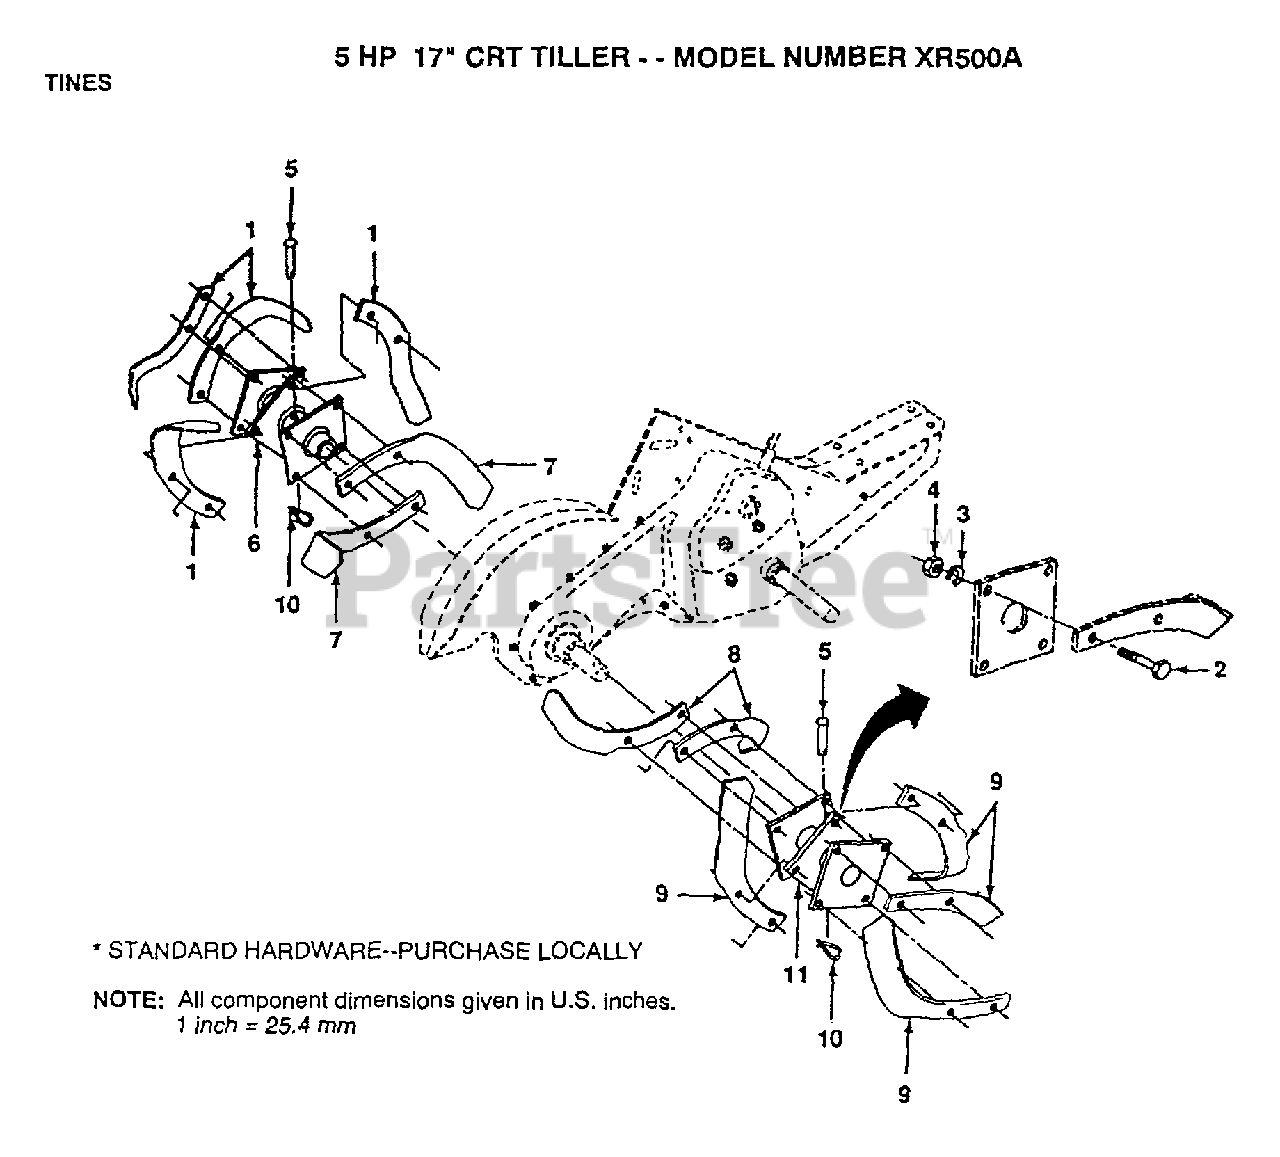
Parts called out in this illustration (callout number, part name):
2	BOLT
3	LOCKWASHER
5	RIVET.PAN HD.1.75
6	TINE ASSY LH CRT
7	"TINE.LH.12"""
8	"TINE.RH.12"""
10	RETAINER.SPRING
11	TINE ASSY RH CRT
